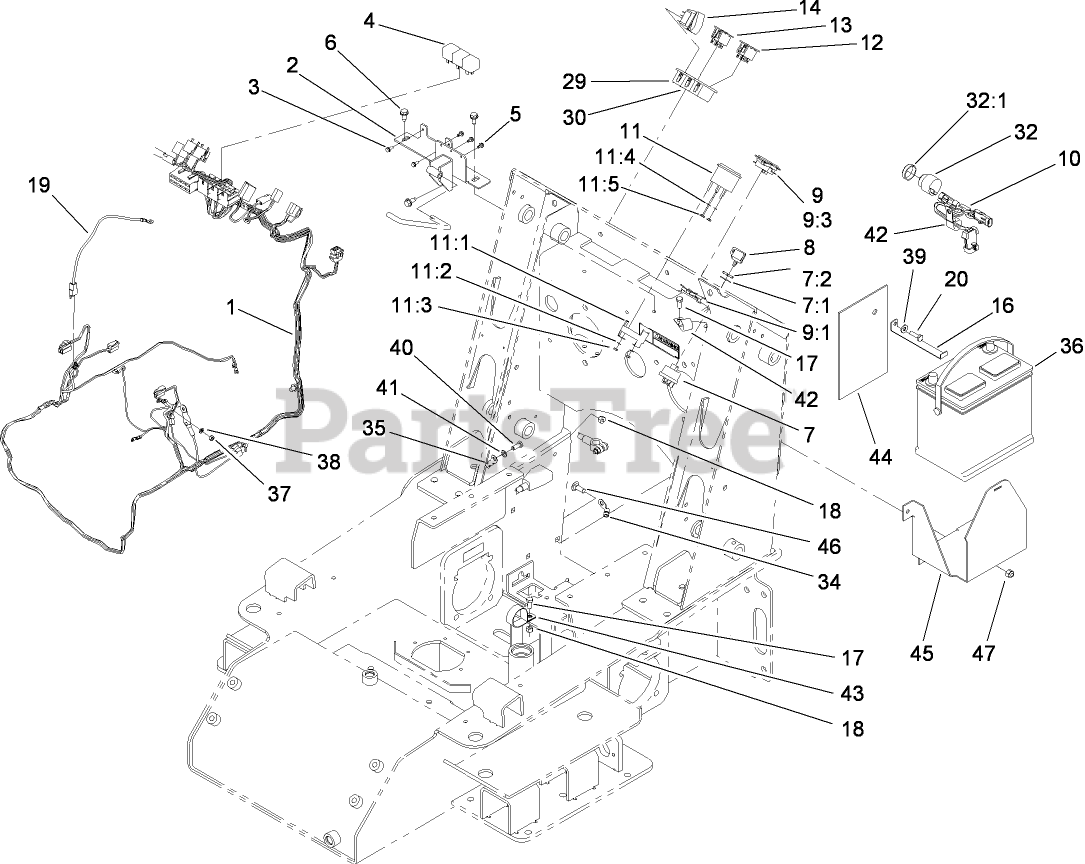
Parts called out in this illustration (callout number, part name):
1	HARNESS-WIRE
2	RELAY BRACKET ASM
3	SCREW
4	RELAY
5	SCREW-HWH
6	SCREW-HWHTF
7	Key Switch ASM
7:1	WASHER-TOOTH, INTERNAL
7:2	NUT-HH
8	KEY-IGNITION
9	METER-HOUR
9:1	CLIP-MOUNTING
9:3	HOUR METER BODY
10	HARNESS-WIRE, NEUTRAL
11	GAUGE-FUEL
11:1	BRACKET-MOUNTING, GAUGE
11:2	WASHER-LOCK, INT
11:3	NUT-HEX
11:4	WASHER-LOCK / EXT
11:5	NUT-HEX
12	LAMP-WARNING
13	LAMP-WARNING
14	SWITCH-ROCKER
16	CLAMP-BATTERY
17	SCREW-HH
18	NUT-LOCK, NI
19	HARNESS-WIRE
20	SCREW-HH
29	BRACKET-END
30	BRACKET-MIDDLE
32	AUDIO ALARM ASM
32:1	NUT-PLASTIC, KNURLED
34	CABLE-BATTERY, POSITIVE
35	CABLE-BATTERY, NEGATIVE
36	BATTERY
37	NUT-HEX
38	WASHER-LOCK, SPRING
39	WASHER-FLAT
40	SCREW-HH
41	WASHER-LOCK
42	CLAMP-J
43	CLAMP-R
44	GUARD-BATTERY
45	MOUNT-BATTERY
46	BOLT-CARR
47	NUT-LOCK, NI
